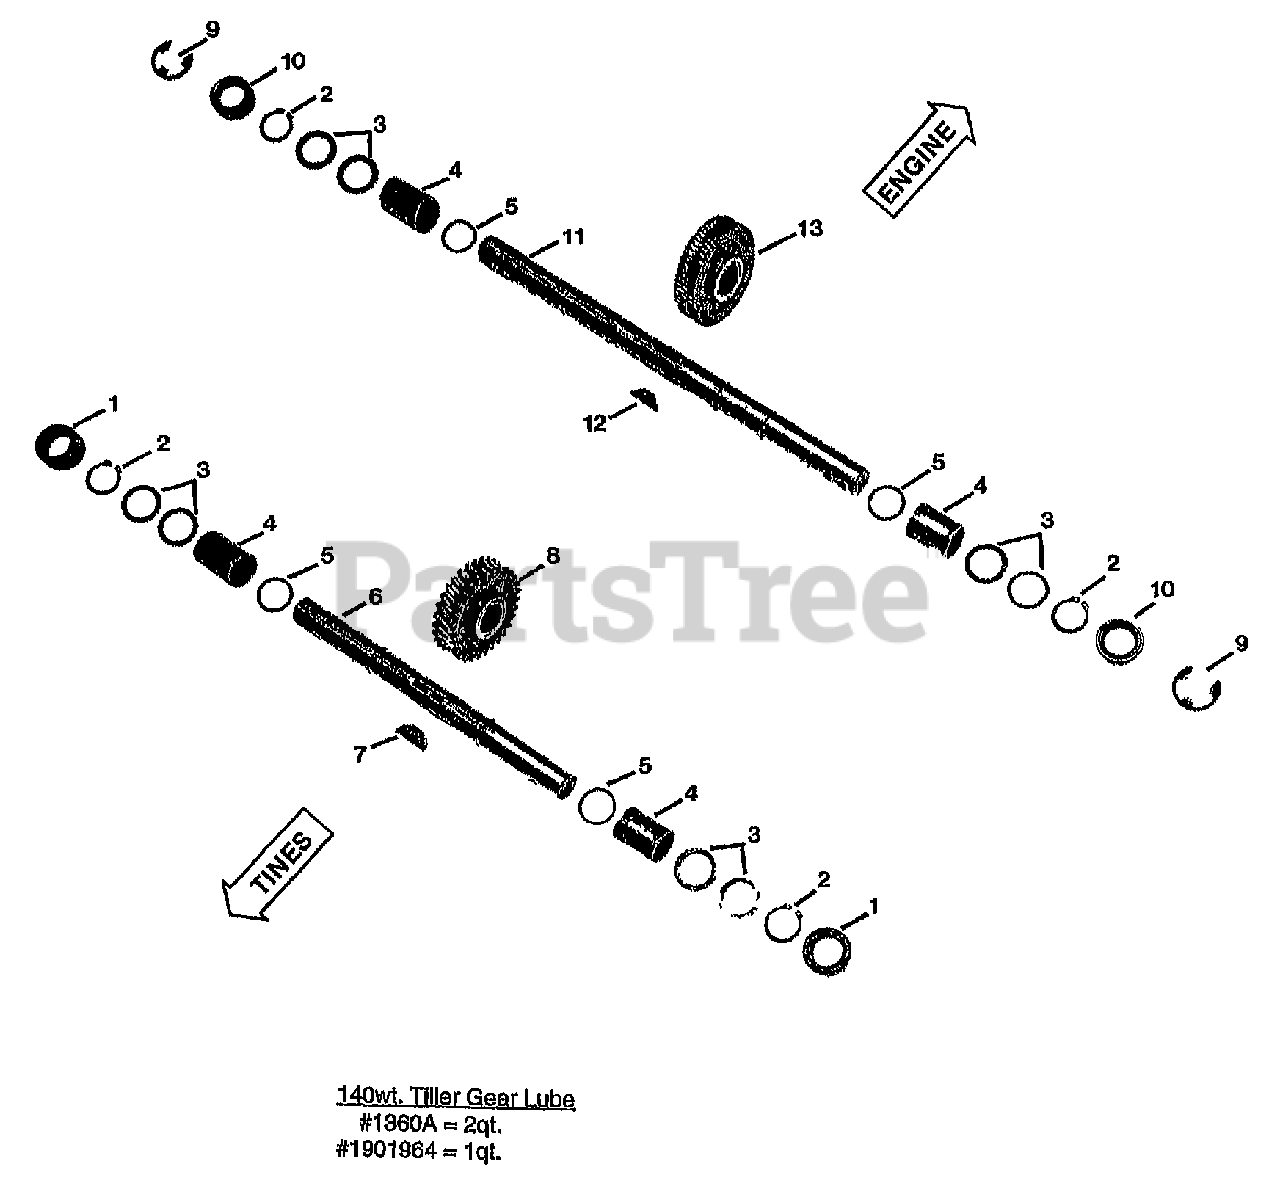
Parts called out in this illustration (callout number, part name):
1	SEAL-OIL TRIPLE LIP (Tiller shaft, LT & RT Sides)
2	RING-HEAVY EXT .906 ID (Tiller and Wheel Shafts)
3	SHIM-1.375X1.015X.062
3	SHIM-1.375X1.015X.03
3	SHIM-1.375X1.015X.015
3	SHIM-1.375X1.015X.01
4	BUSHING-1.25X1.005X1.5 bronze, (Tiller and Wheel Shafts, LT & RT sides)
5	SHIM-1.234X1.015X.062 (Tiller and Wheel Shafts)
6	TILLER SHAFT-W/KEY (Inc. 6)
7	KEY-WOODRUFF .25X1.12 (Tiller shaft to worm gear)
8	GEAR-WORM BRONZE MACH (Tiller Drive)
9	RING-RETAINING 5133-989 (E-type retaining, external, LT & RT sides)
10	SEAL-OIL WHEELSHAFT (LT & RT sides)
11	WHEELSHAFT-W/KEY (Inc. 12)
12	KEY-HI PRO .25X1.062 (Wheel shaft to worm gear)
13	GEAR-WORM 61 TEETH MACH bronze, (Wheel drive)
